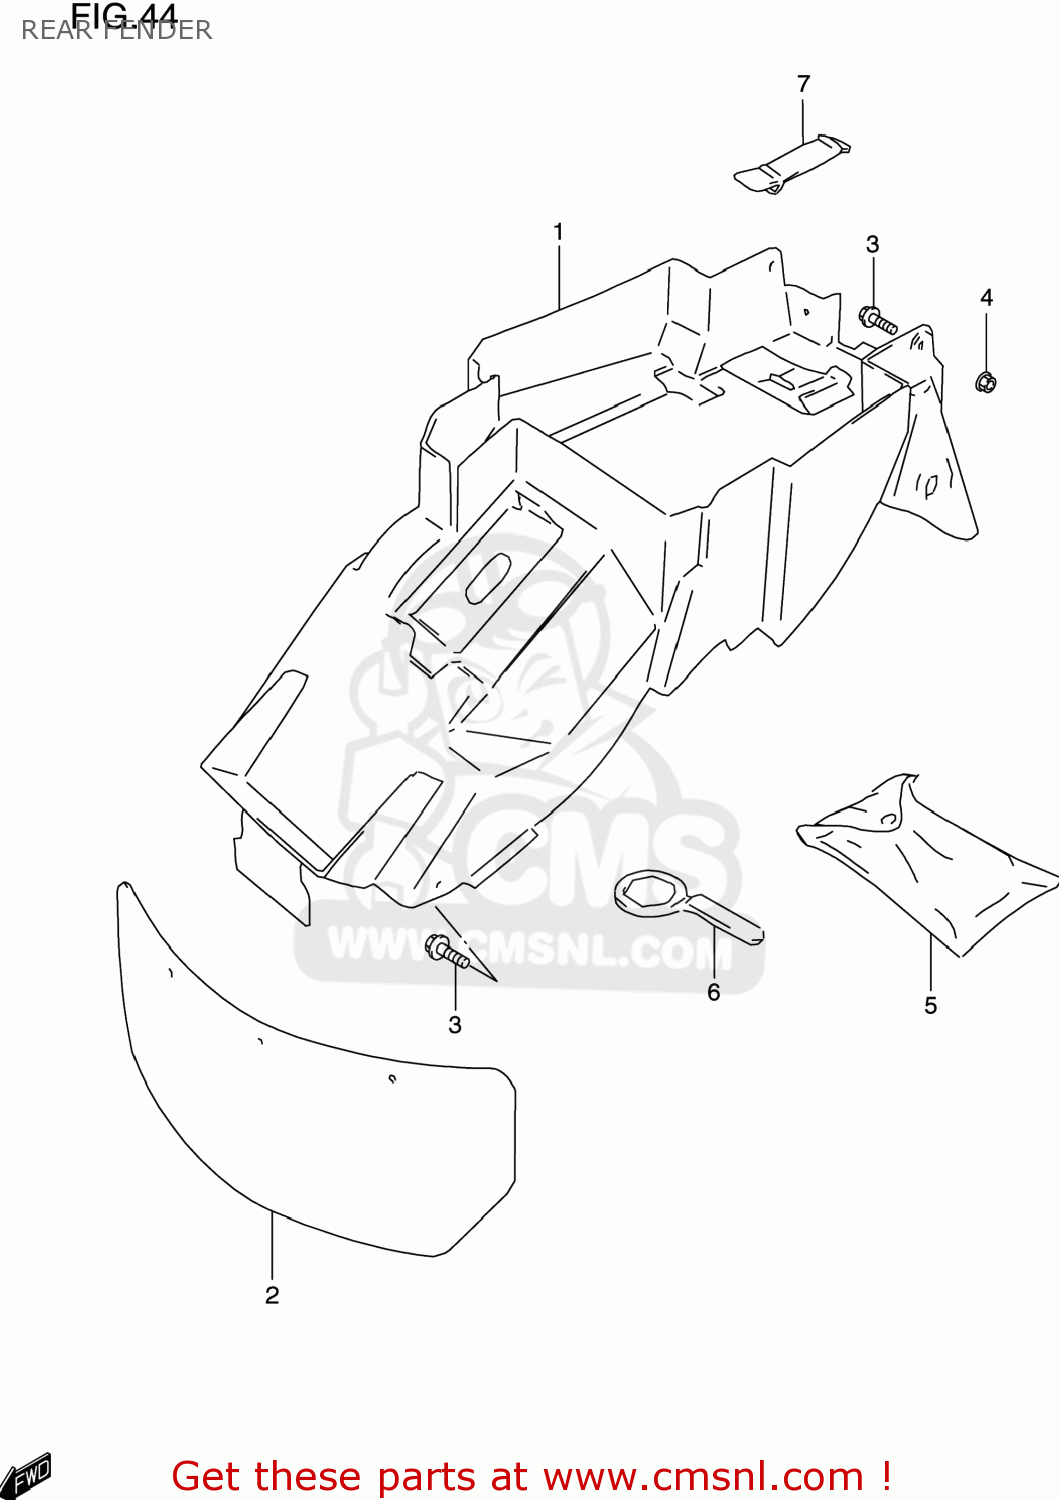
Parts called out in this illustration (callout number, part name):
1	FENDER,RR
2	MUDGUARD,RR FENDER
3	BOLT(6X16)
4	NUT
5	TOOL ASSY
6	RING SPANNER(36)
7	BAND
